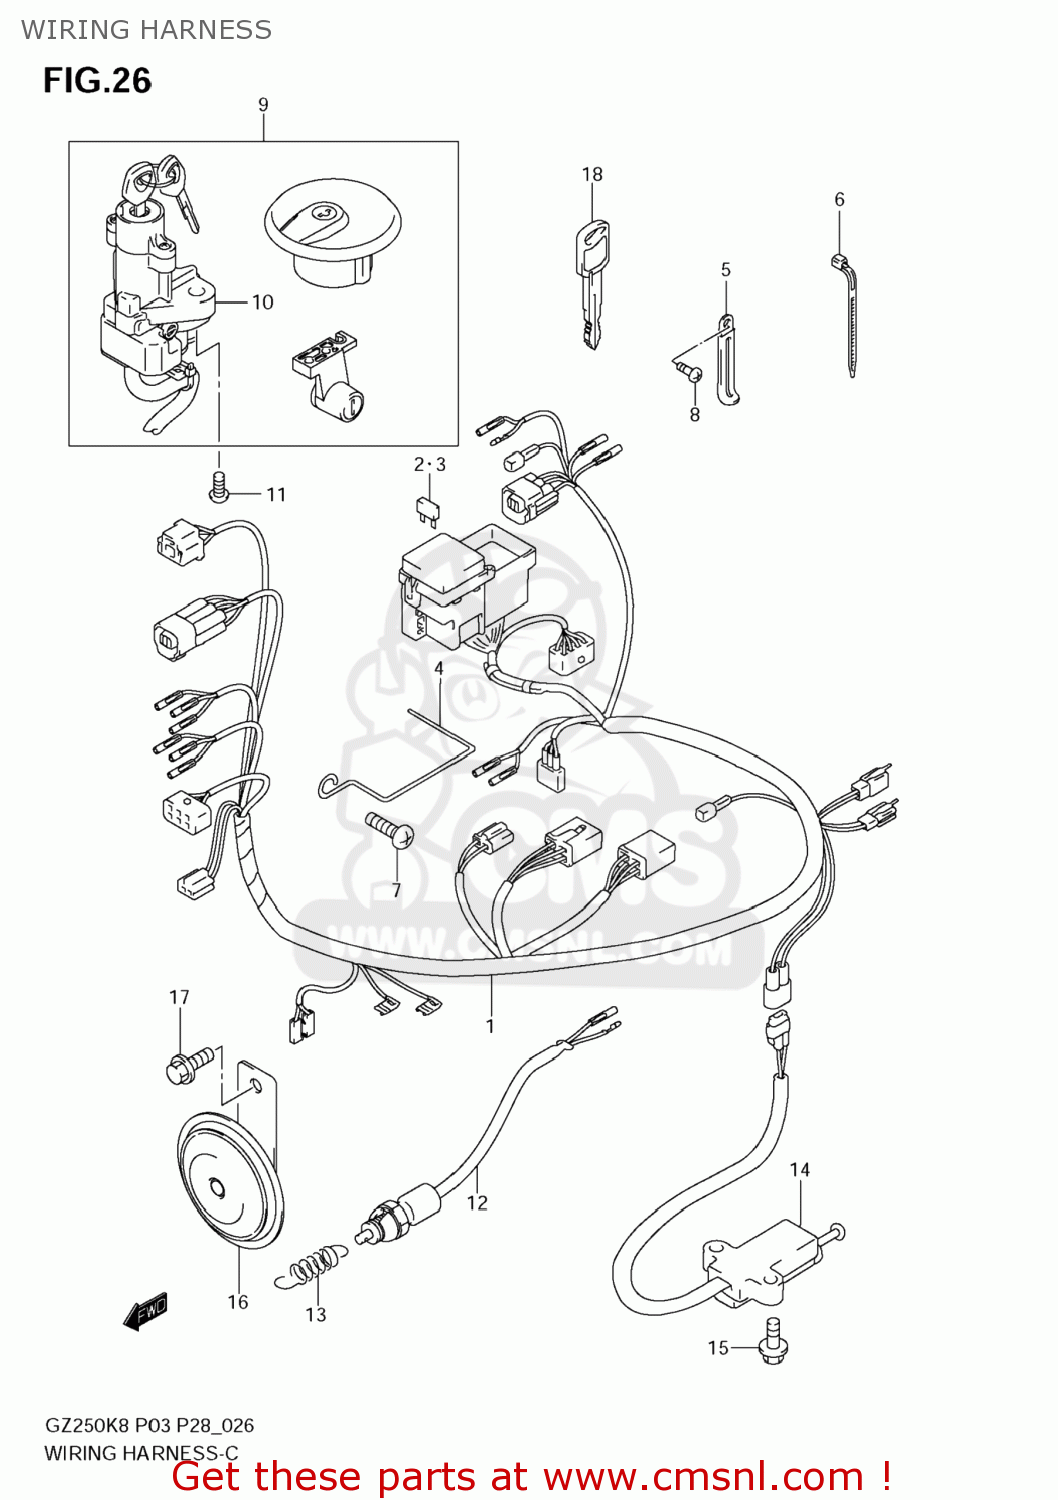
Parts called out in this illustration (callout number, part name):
1	HARNESS, WIRIN
2	FUSE(10A)
3	FUSE(15A)
4	GUIDE,HARNESS
5	CLAMP(L:45)
6	CLAMP(L:95)
7	BOLT
8	SCREW
9	LOCK SET
10	LOCK ASSY,STEERING
11	BOLT(8X20)
12	SWITCH ASSY,STOP LAMP
13	SPRING
14	SWITCH ASSEMBLY,SIDE STAND
15	BOLT
16	HORN ASSY
17	BOLT
18	KEY,BLANK
